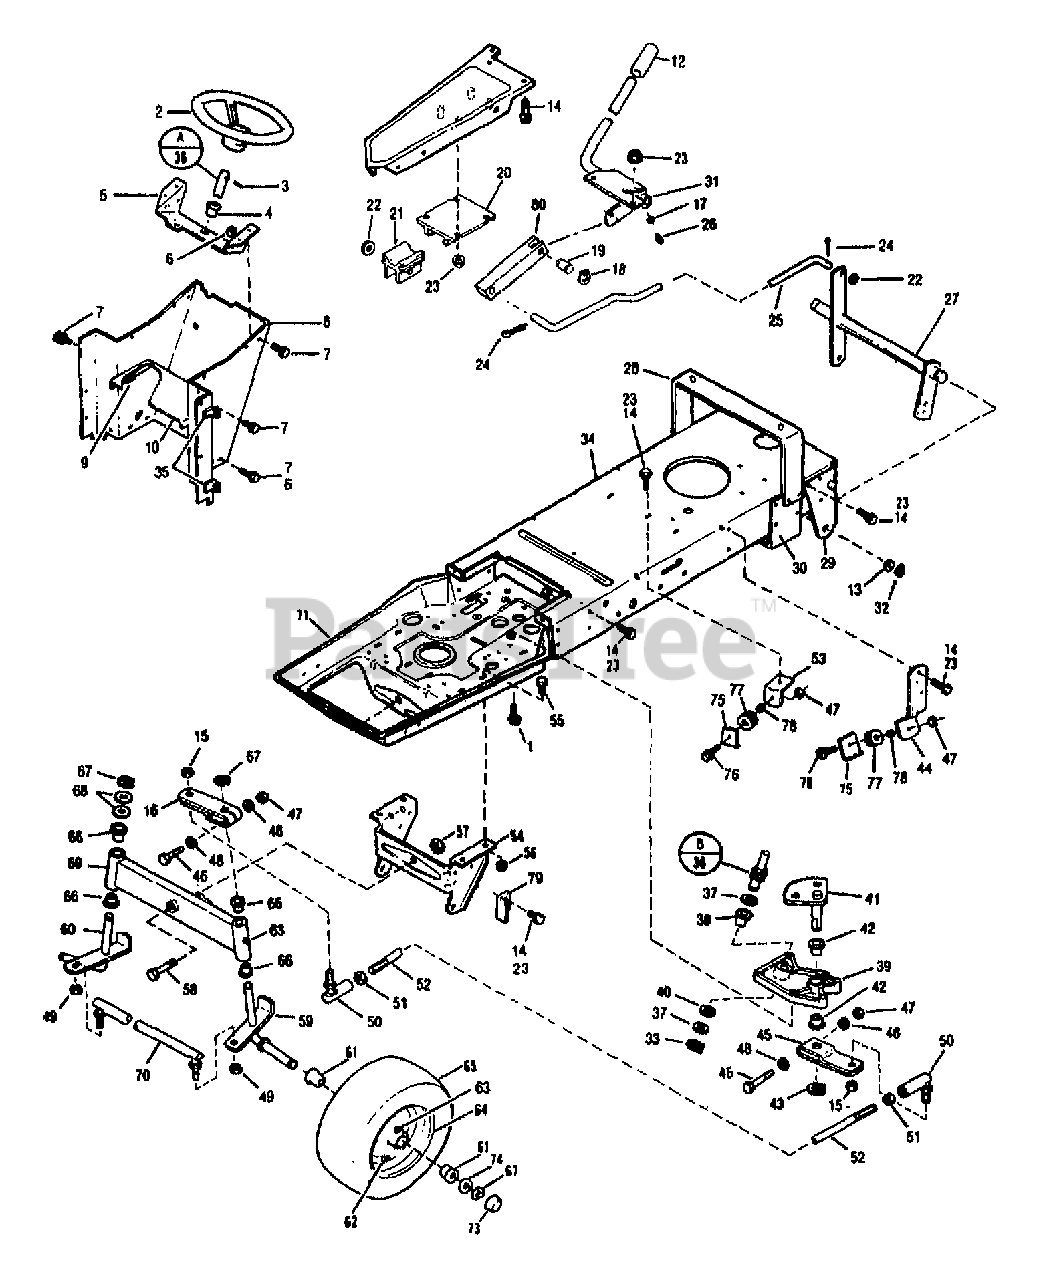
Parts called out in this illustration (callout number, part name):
1	SCR-HFLK 5/16-18X.75
2	WHEEL-STEERING
4	BEARING-FLANGED NYLON
5	SUPPORT-STEERING SHAFT
6	NUT-HF/LK 1/4-20 ZP
7	SCR-HH 1/4-20X.625
9	NUT-SPEED
10	SUPPORT-BATTERY
12	GRIP-FLEX
13	WASHER-1.38 X.765X .06 ZP
14	SCR-LOCK
15	NUT-HEX/JAM 1/2-20 ZP
16	ARM-STEERING
17	WASHER
18	RING-RETAINING
20	KIT-GUIDE (TRACTOR)
21	KIT-GUIDE (TRACTOR)
23	NUT-HFLK 5/16-18 ZP
25	ROD-LIFT
26	FITTING-GREASE
27	ASSM-LIFT SHAFT
29	ASSM-PANEL REAR
30	AXLE-SUPPORT
31	ASSM-LIFT LEVER
32	RING-RET."E".577 ID
33	RING-RETAINING
35	NUT-SPEED
36	SHIFT-STEER
37	WASHER-SHIM
38	BEARING
39	ASSM-STEER SUPT
40	WASHER-1.115X.637X.06
41	ASSM-SECTOR GEAR
42	BEARING-FLANGE
43	RING-RETAIN EXT .707 ID
44	BRACKET
45	ASSM-ARM SPINDLE
47	NUT-LOCK 3/8-16
48	WASHER-.875X.390X.134
49	NUT-LOCK
50	JOINT-BALL
51	NUT-JAM
52	ROD-STEERING
53	BRACKET
54	BRKT-ATTACHMENT
56	NUT-HFLK 3/8-16 ZP
57	NUT-H/LK 5/8-11
58	SCR-HH 5/8-11X2.25 G5 ZP
59	ASSM-SPINDLE LH
60	ASSM-SPINDLE RH
61	BUSHING
62	STEM-VALVE
63	FITTING-GREASE 1/4-28X2.00
64	WHEEL-RED
65	TIRE
66	BUSHING
67	RING-RET."E".577 ID
68	WASHER-1.25X.765X.049
69	ASSM-FRONT AXLE
70	ROD-TIE
71	FRAME-FRONT
73	CAP-WHEEL
74	WASHER-1.38 X.765X .06 ZP
75	GUIDE-CABLE
77	PULLEY-CABLE
78	SPACER-.75X.40X.51 P/M
79	BRACKET
